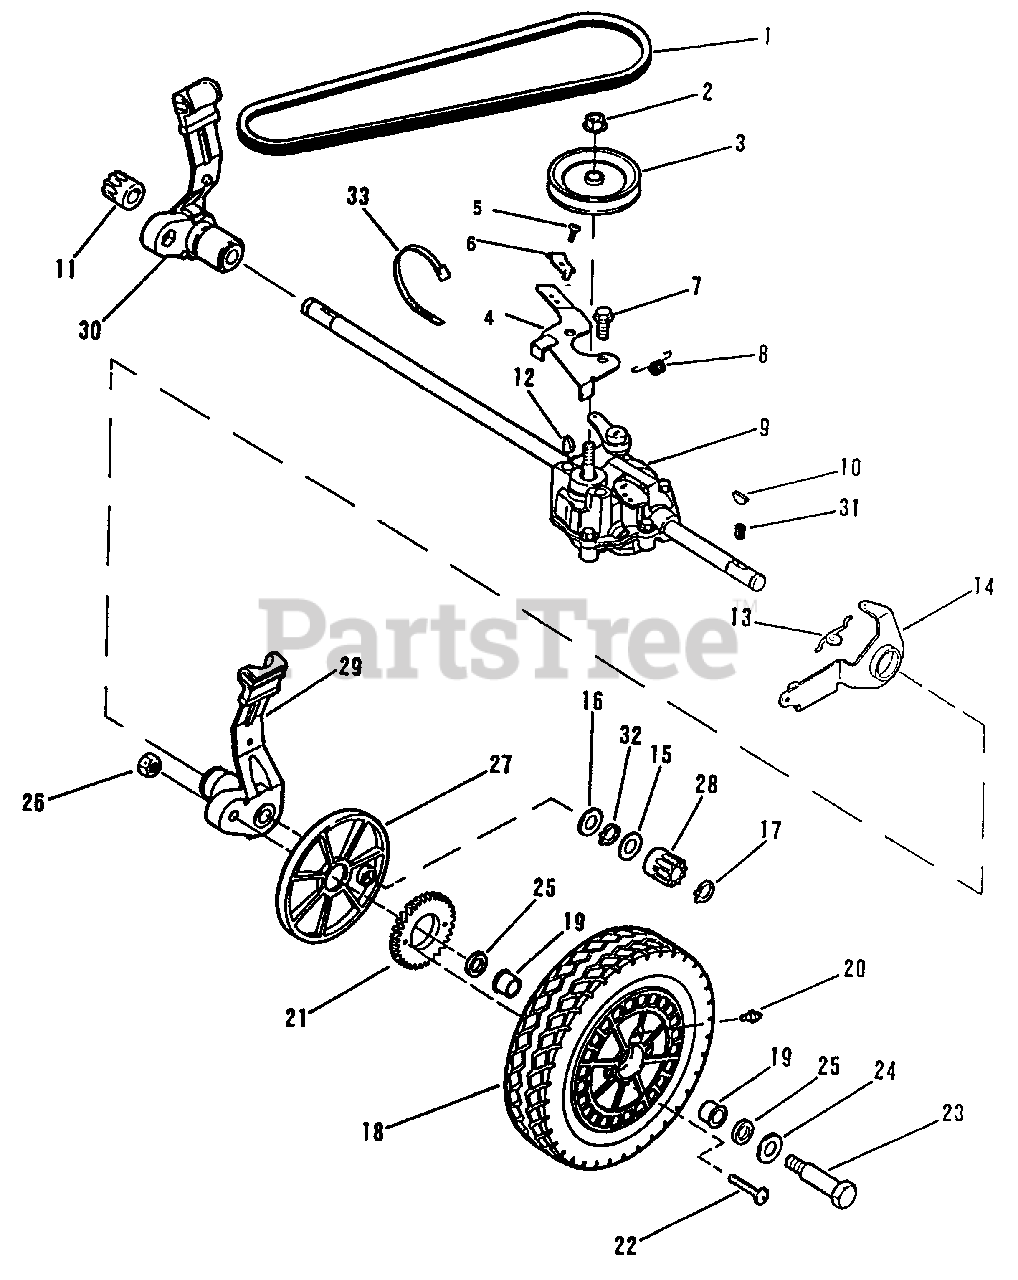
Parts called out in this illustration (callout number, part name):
1	V-Belt
2	Nut
3	Transmission Pulley
4	Linkage Plate & Screw Kit
5	Screw-Clamp to Linkage Plate
6	Clamp
7	Screw-Plate to Transmission
8	Spring
9	Transmission
10	Key
11	Drive Pinion-Right Wheel
12	Key
13	Link
14	Actuator Arm and Bushing
15	Washer
16	Thrust Washer
17	Retaining Ring
18	Wheel, Tire and Bearing Assy.
19	Flange Bearing
20	Grease Fining
21	Gear
22	Screw-Gear to Wheel
23	Shoulder Bolt-Rear Wheel
24	Washer
25	Felt Washer
26	Nut
27	Wheel Cover
28	Drive Pinion-Left Wheel
29	Height Adjustment Assembly-L.H.
30	Height Adjustment Assembly-R.H.
31	Spring
32	Retaining Ring
33	Tie Strap
